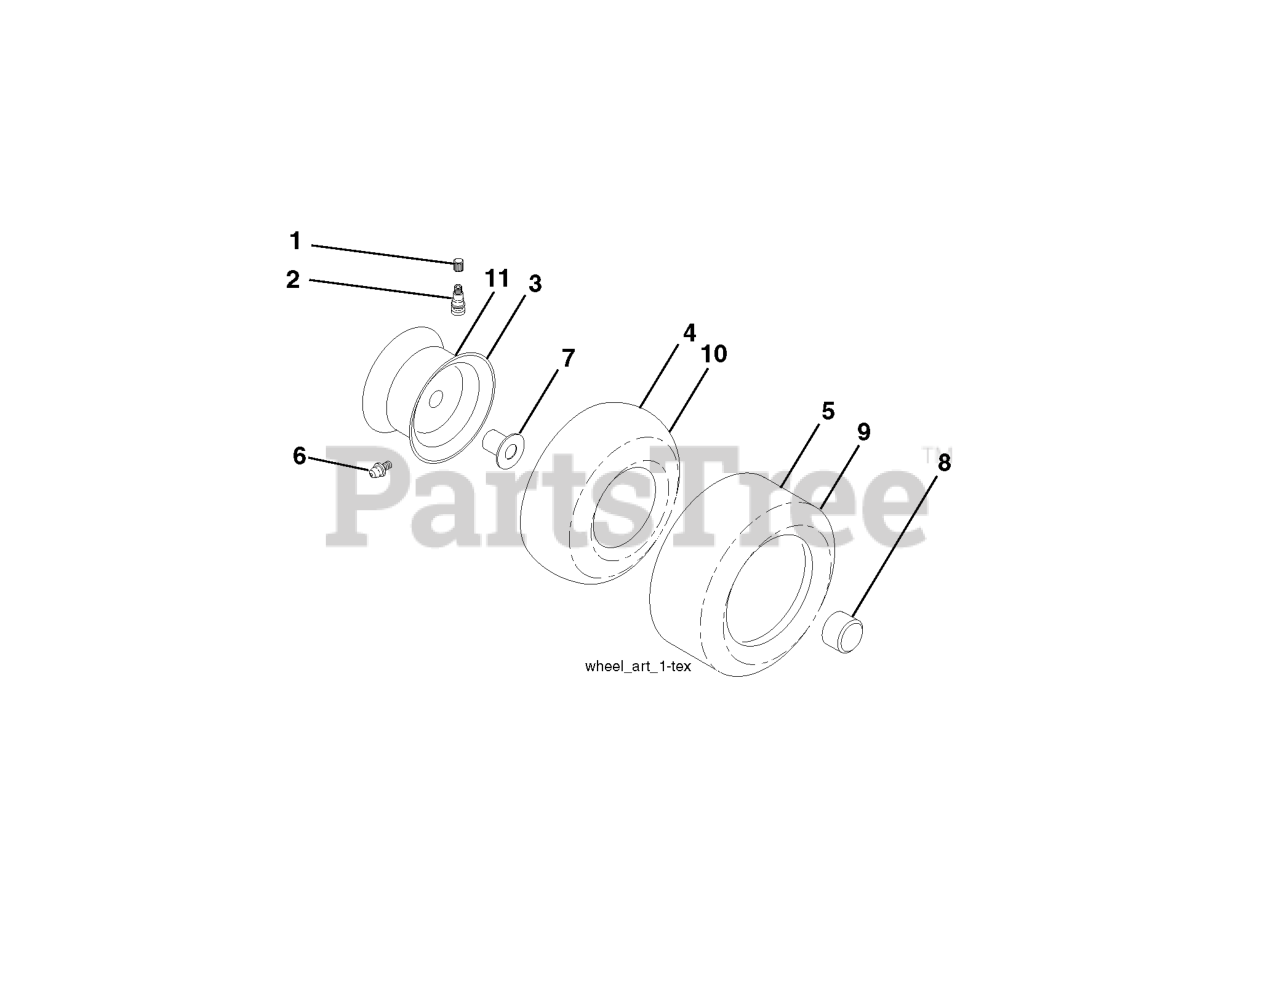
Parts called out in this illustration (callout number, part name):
1	Cap, Valve, Tire (AYP part number)
2	Stem, Valve (AYP part number)
3	RIM.ASM.6"FRONT.MATTE.BLACK
4	Tube, Tire, Front (Not Supplied, Service Item Only)
5	Tire F Ts 15 X 6 0 - 6 Service (AYP part number)
6	Fitting, Grease (Front Wheels Only) (AYP part number)
7	Bearing Flange (Service Item Only) (AYP part number)
8	CAP, AXLE BLK
9	TIRE 20X8-8 TURF SAVER
10	Tube, Rear (Optional Service Item Only) (AYP part number)
11	RIM.ASM.8'REAR.MATTE.BLACK
